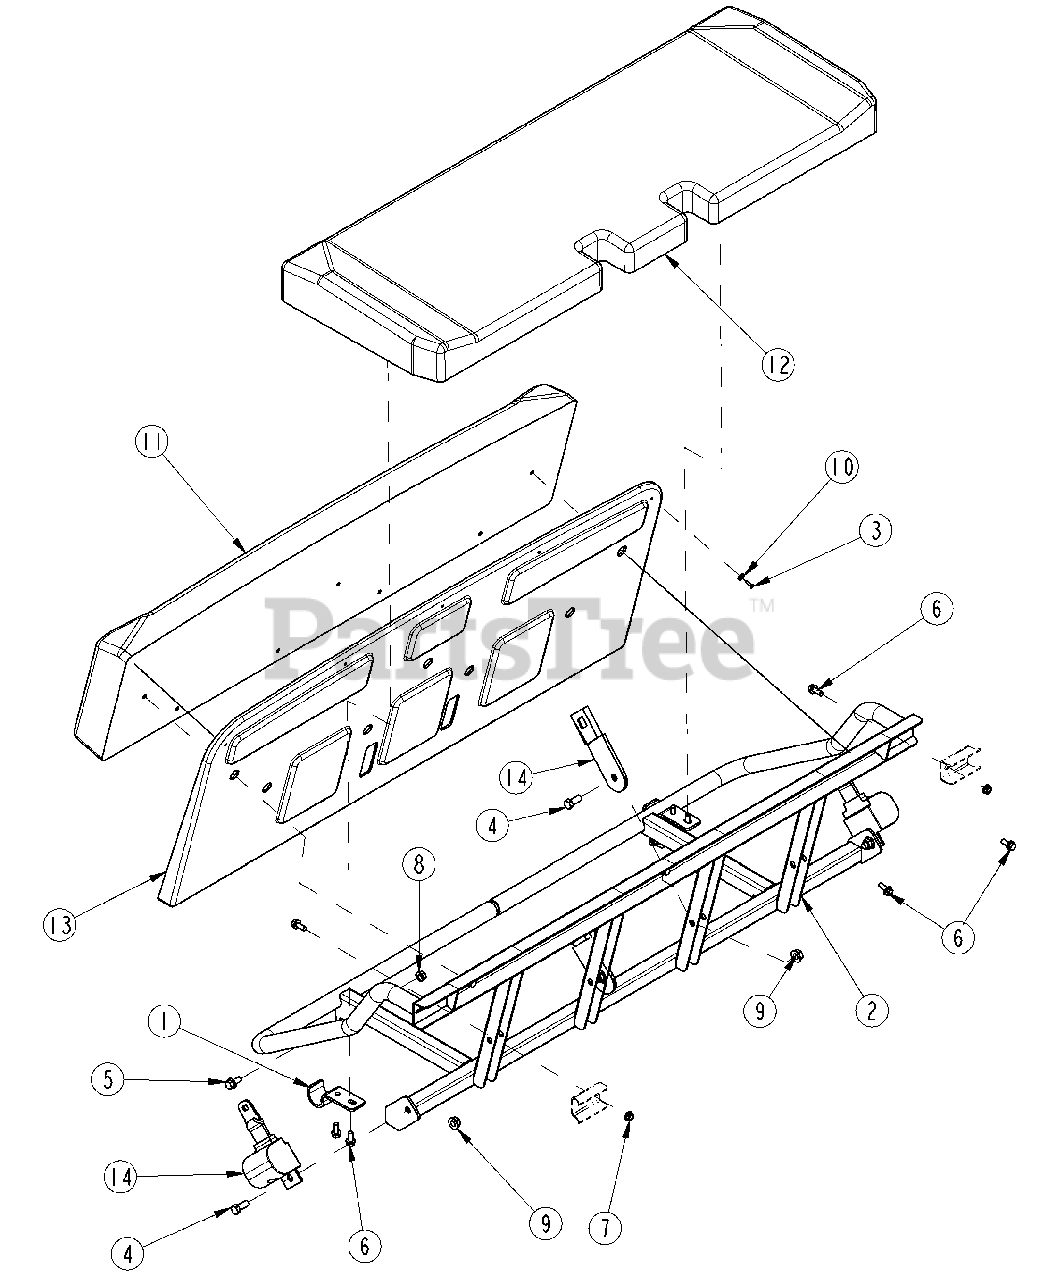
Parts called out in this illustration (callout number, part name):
1	SEAT PIVOT PLATE
2	BENCH SEAT WELDMENT
3	SCREW, OVPH SM 8 X 3/4 SS
4	BOLT, HEX 7/16-14 X 1 GR5
5	HFSS 3/8-16X3/4 LG
6	HFS 5/16-18X3/4 GR5
7	NUT HEX FLG TP LK 5/16-18ZNYCR
8	NUT FLANGE LOCK 3/8-16 PLT
9	NUT HEX FLANGE LOC 7/16-14 PLT
10	WASHER, #8 FINISH CUP
11	BENCH SEAT BACK TAN (ST)
12	BENCH SEAT BACK CUSH, BLACK
13	BENCH SEAT BOTTOM TAN (ST)
14	BENCH SEAT BOTTOM CUSH, BLACK
